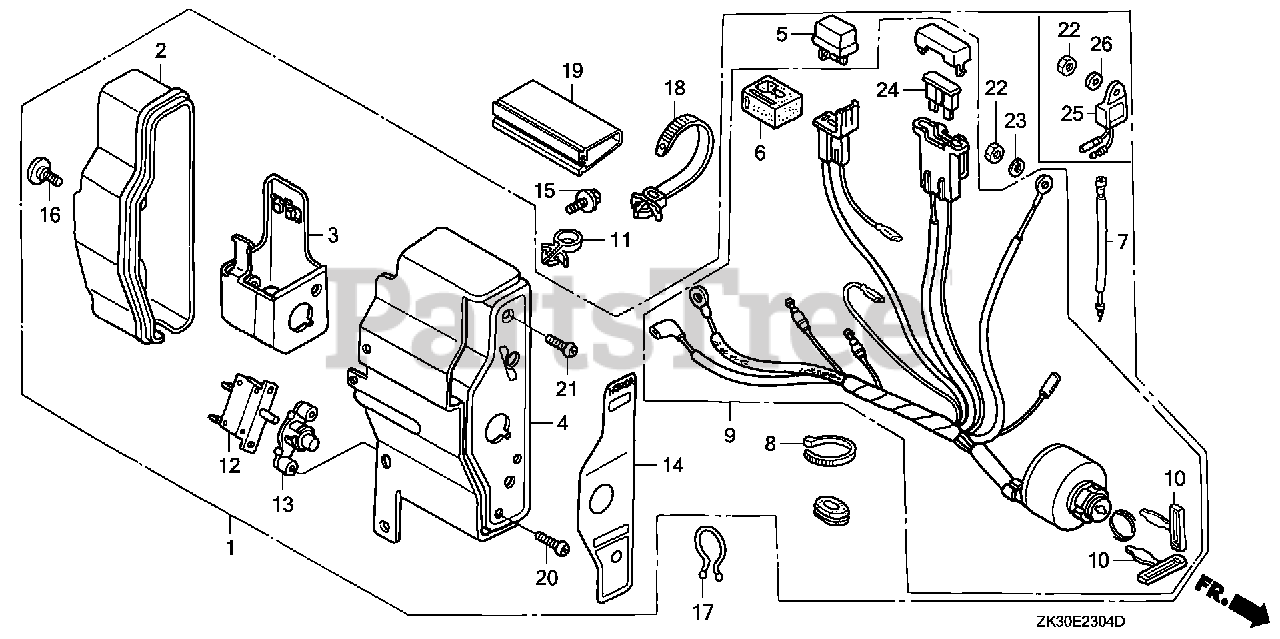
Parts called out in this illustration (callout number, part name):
1	BOX ASSY., CONTROL *NH1* (ALERT) (BLACK)
1	BOX ASSY., CONTROL *R8* (ALERT) (BRIGHT RED)
2	CASE, CONTROL
3	BRACKET, CASE MOUNTING
4	PANEL, CONTROL *NH1* (BLACK)
4	PANEL, CONTROL *R8* (BRIGHT RED)
4	PANEL, CONTROL *R280* (POWER RED)
5	RECTIFIER ASSY., SILICON (SHINDENGEN)
6	SUSPENSION, CONNECTOR
7	SUB-WIRE HARNESS
9	SWITCH ASSY., COMBINATION
10	KEY (HONDALOCK)
11	HOLDER, STOP SWITCH WIRE
12	PROTECTOR, CIRCUIT (1.0A)
13	LENS ASSY., PROTECTOR
14	MARK, CONTROL BOX (EXP)
15	BOLT, FLANGE (6X12) (CT200)
16	SCREW, SPECIAL (6X12)
17	CLIP, PURSE LOCK
18	STRAP, CABLE (118MM) (BLACK)
19	TUBE, FASTENER (30MM)
20	SCREW, PAN (3X12)
21	SCREW, PAN (4X12)
22	NUT, HEX. (4MM)
23	WASHER, SPRING (4MM)
24	FUSE, BLADE (5A)
